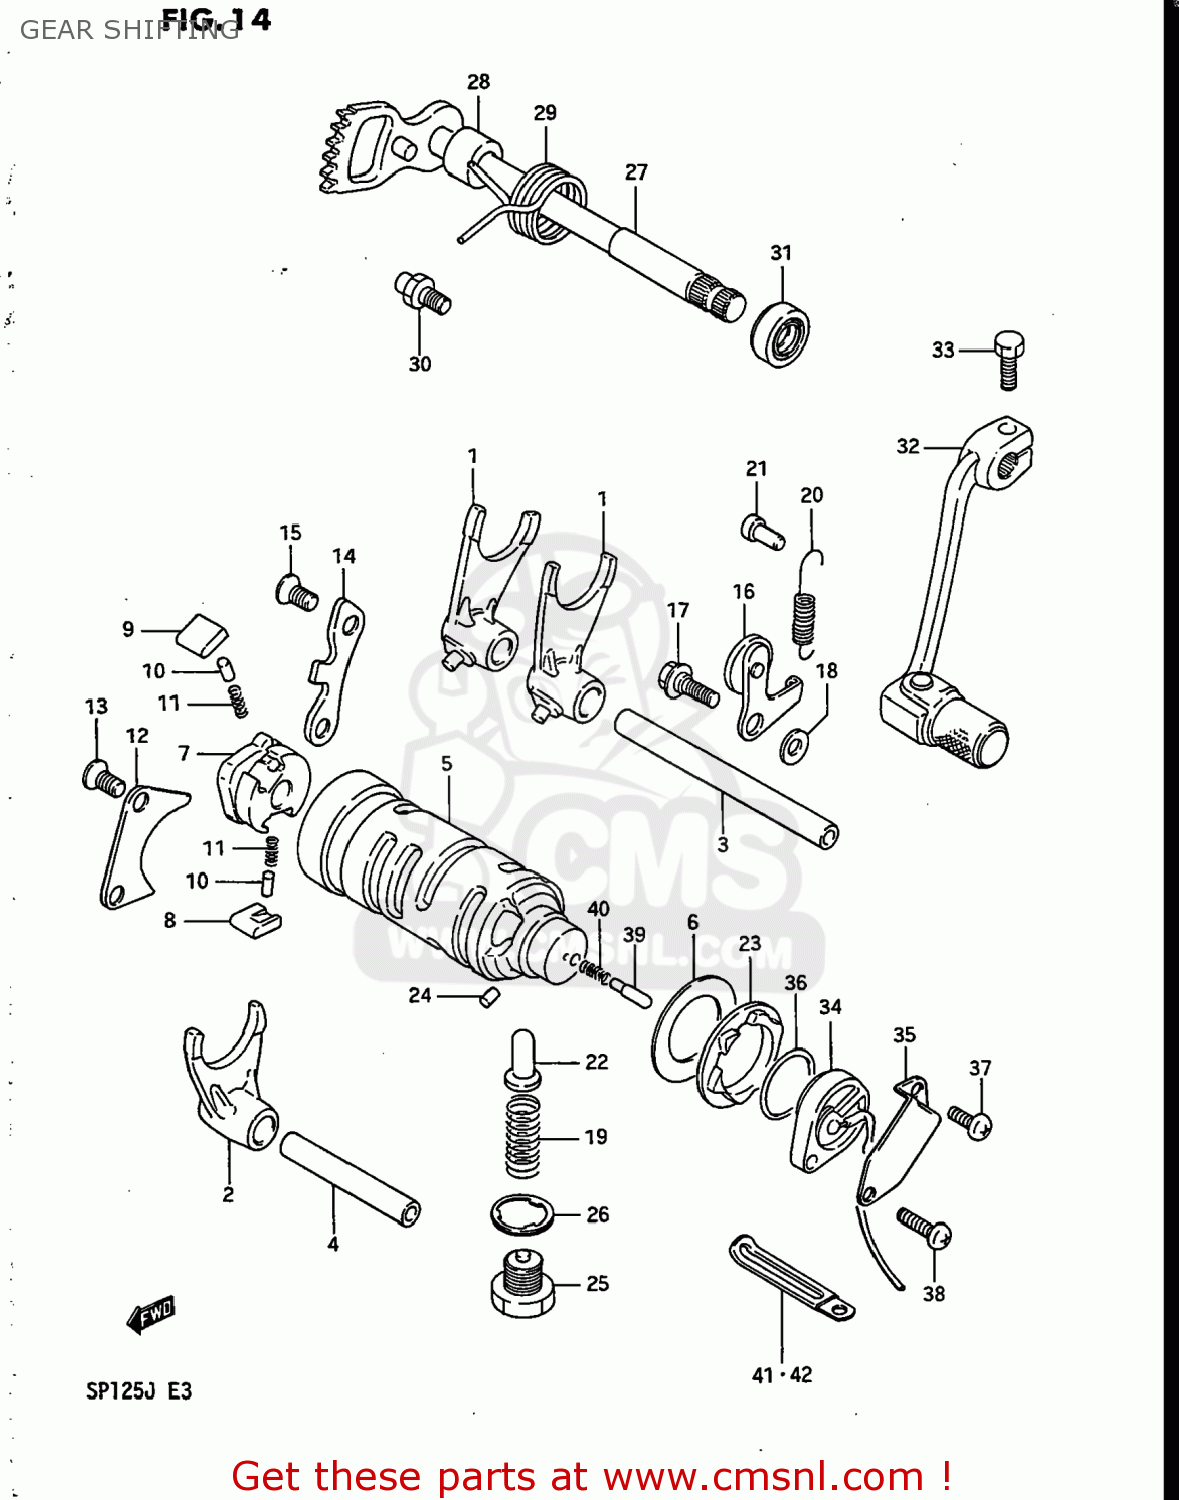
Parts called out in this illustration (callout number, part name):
1	FORK,GEAR SHIFT NO.1
2	FORK,GEAR SHIFT NO.3
3	SHAFT,GEAR SHIFT FORK(L:109)
4	SHAFT,GEAR SHIFT FORK
5	CAM,GEAR SHIFT
6	WASHER,THRUST
7	GEAR,GEARSHIFT CAM DRIVE
8	PAWL,GEAR SHIFT NO.1
9	PAWL,GEAR SHIFT NO.2
10	PIN(5X8)
11	SPRING
12	LIFTER,GEAR SHIFT POLE
13	SCREW
14	GUIDE,GEAR SHIFT CAM
15	SCREW
16	STOPPER,GEAR SHIFT CAM
17	BOLT
18	WASHER
19	SPRING
20	SPRING
21	RIVET
22	STOPPER,GEAR SHIFT CAM NO.2
23	PLATE,GEAR SHIFT CAM STOPPER
24	PIN 4X6
25	PLUG (14X12)
26	GASKET(14X19.2X2) (NAS)
27	SHAFT,GEAR SHIFT
28	SPACER(12X20X15.3)
29	SPRING
30	STOPPER,GEAR SHIFT CAM
31	OIL SEAL
32	LEVER ASSEMBLY,GEAR SHIFTING
33	BOLT
34	BASE ASSEMBLY,GEAR SHIFT TERMINAL
35	PROTECTOR,GEAR SHIFT SW
36	O-RING (D:2.4 ID:22.2)
37	SCREW
38	SCREW
39	PIN(5X15.5)
40	SPRING
41	CLAMP
42	CLAMP
